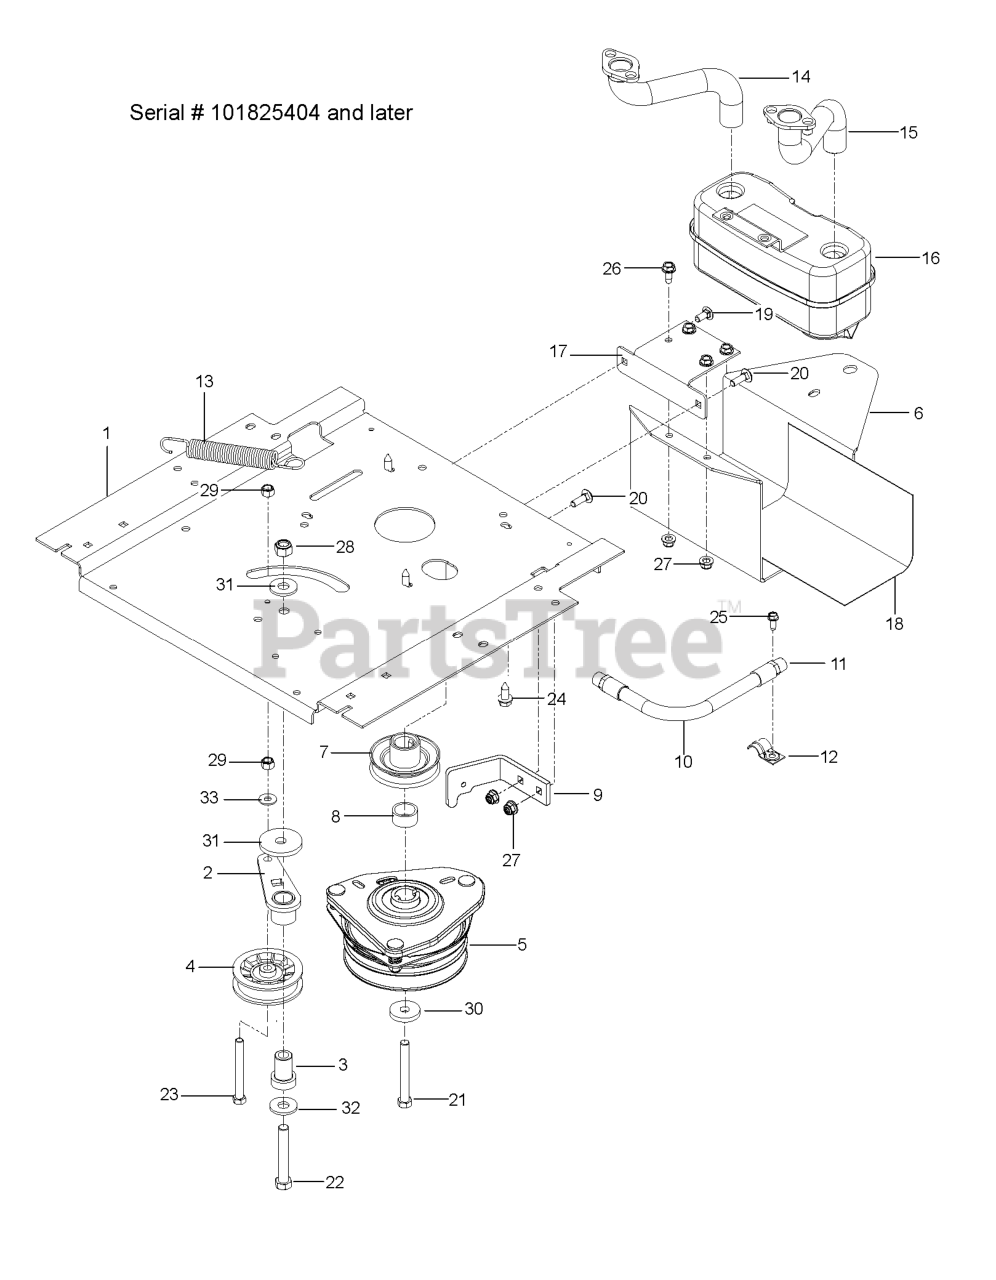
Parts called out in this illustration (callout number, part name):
1	PLATE ENGINE, BLACK
2	RP.IDLER ARM WELDMENT
3	PIVOT, IDLER
4	PULLEY, IDLER RAKE & ZTR
5	CLUTCH MZ ZTR GT.48/54"1.125"
6	GUARD, MUFFLER, BLACK
7	PULLEY, ENGINE
8	SPACER, CLUTCH, 0.600
9	STOP, CLUTCH, OGURA BLK
10	OIL DRAIN HOSE
13	SPRING, DECK DRIVE
14	RP.PIPE-EXHAUST LH
15	RP.PIPE-EXHAUST RH
16	MUFFLER ASM TWIN
17	BRACKET, MUFFLER, BLACK
18	HEAT SHIELD
19	RP BOLT 5/16-18 X3/4 ZN/YEL GR
21	BOLT 7/16F X 2 1/2
22	HCS 1/2C X 2 3/4
23	HCS 3/8-16X3 1/2 GR5
24	HHFS 3/8-16 X 1.0 THD FORMING
25	SCREW 1/4 X 5/8
26	BOLT 5/16-18 X 3/4
27	5/16-18 NYLOC FLANGE NUT
28	NUT.LK.W/WSH.1/2.
29	NUT 3/8-16 NYLOC
31	HEAVY WASHER
32	WASHER.9/16 X 1 3/8 X 12 GA.
33	WASHER 5/16 FLAT
